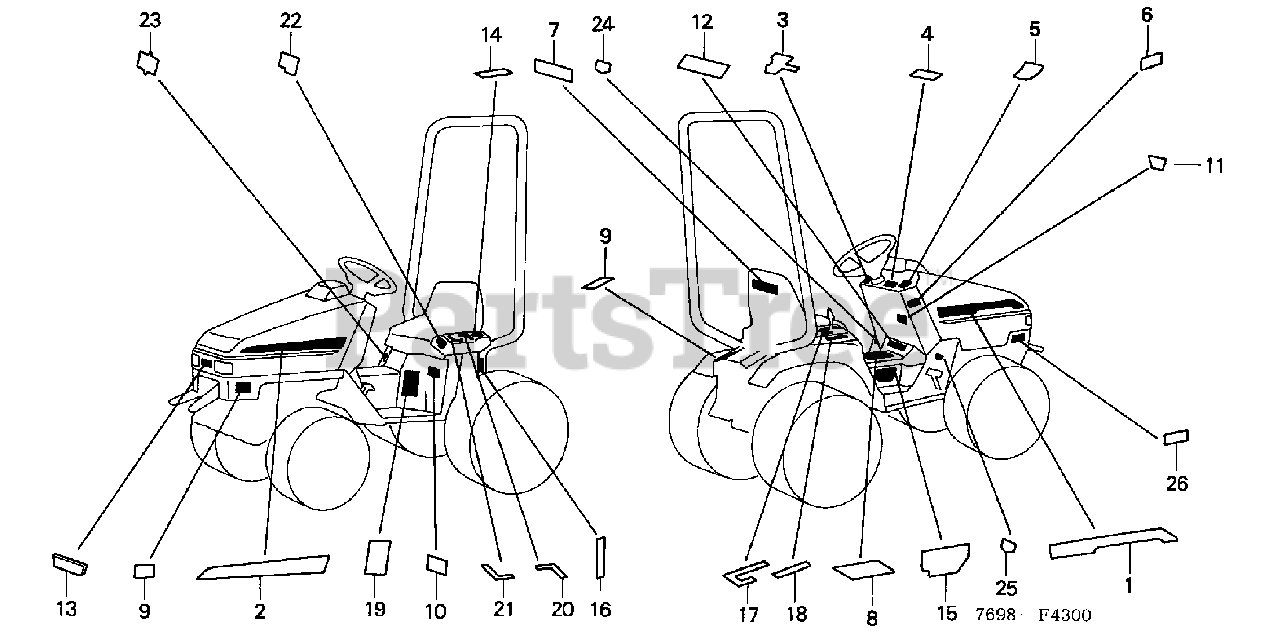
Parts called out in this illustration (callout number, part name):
1	MARK, R. SIDE STRIPE
2	MARK, L. SIDE STRIPE (4WS)
3	MARK, LIGHT OPERATION (ENGLISH)
4	MARK, ENGINE SWITCH (ENGLISH)
5	MARK, THROTTLE OPERATION (ENGLISH)
6	MARK, P.T.O. INDICATION
7	MARK, SEAT
8	LABEL, WARNING (ENGLISH)
9	LABEL B, WARNING (ENGLISH)
10	LABEL, FUEL WARNING (B)(ENGLISH)
11	MARK, BRAKE LOCK INDICATION (ENGLISH)
12	LABEL, PARKING BRAKE (ENGLISH)
13	EMBLEM, HOOD
14	MARK, P.T.O. INDICATION (ENGLISH)
16	LABEL, ROLL OVER PROTECTIVE STRUCTURE WARNING (ENGLISH)
17	MARK, LIFT INDICATION (ENGLISH)
18	LABEL, HYDRAULIC ADJUST OPERATION (ENGLISH)
19	MARK, RECOMMENDED WORK SPEED (ENGLISH)
20	MARK A, MAIN CHANGE INDICATION (ENGLISH)
21	MARK B, MAIN CHANGE INDICATION (ENGLISH)
22	MARK, SUB-CHANGE INDICATION (ENGLISH)
24	MARK, CLUTCH INDICATION (ENGLISH)
25	MARK, BRAKE INDICATION (ENGLISH)
26	MARK, EX. CAUTION (A)
